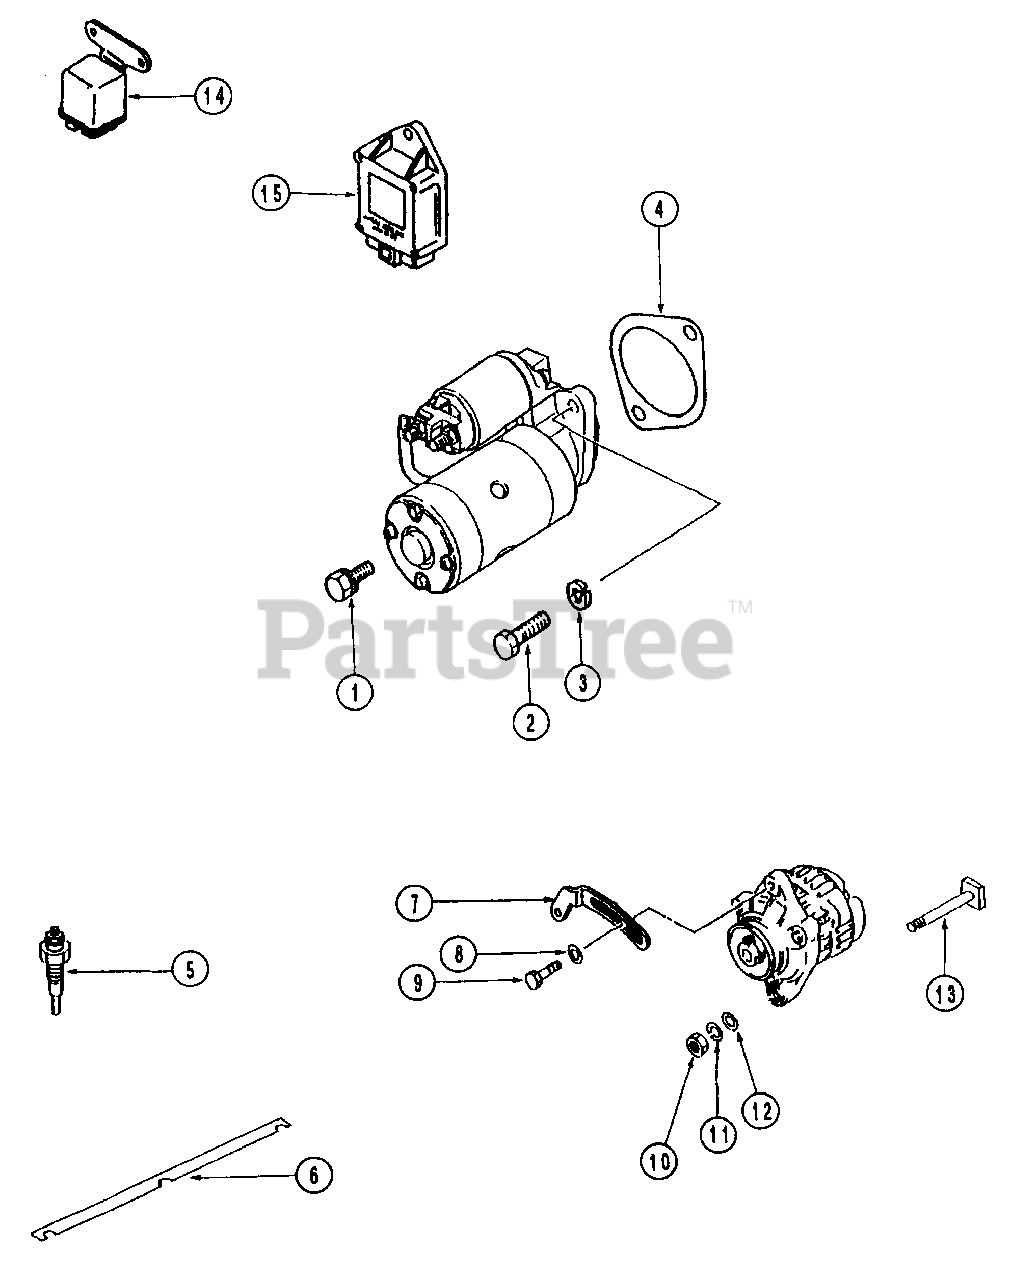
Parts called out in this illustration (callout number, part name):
1	Bolt, W/Washer
2	Bolt, Starter
3	Spring, Washer
4	Gasket, Starter
5	Plug, Glow
6	Plate, Connection
7	Plate, Adjusting
9	Bolt, Flange
11	Spring, Washer
12	Washer, Plain
13	Bolt, Alternator
14	Relay, Glow
15	Controller, Glow
